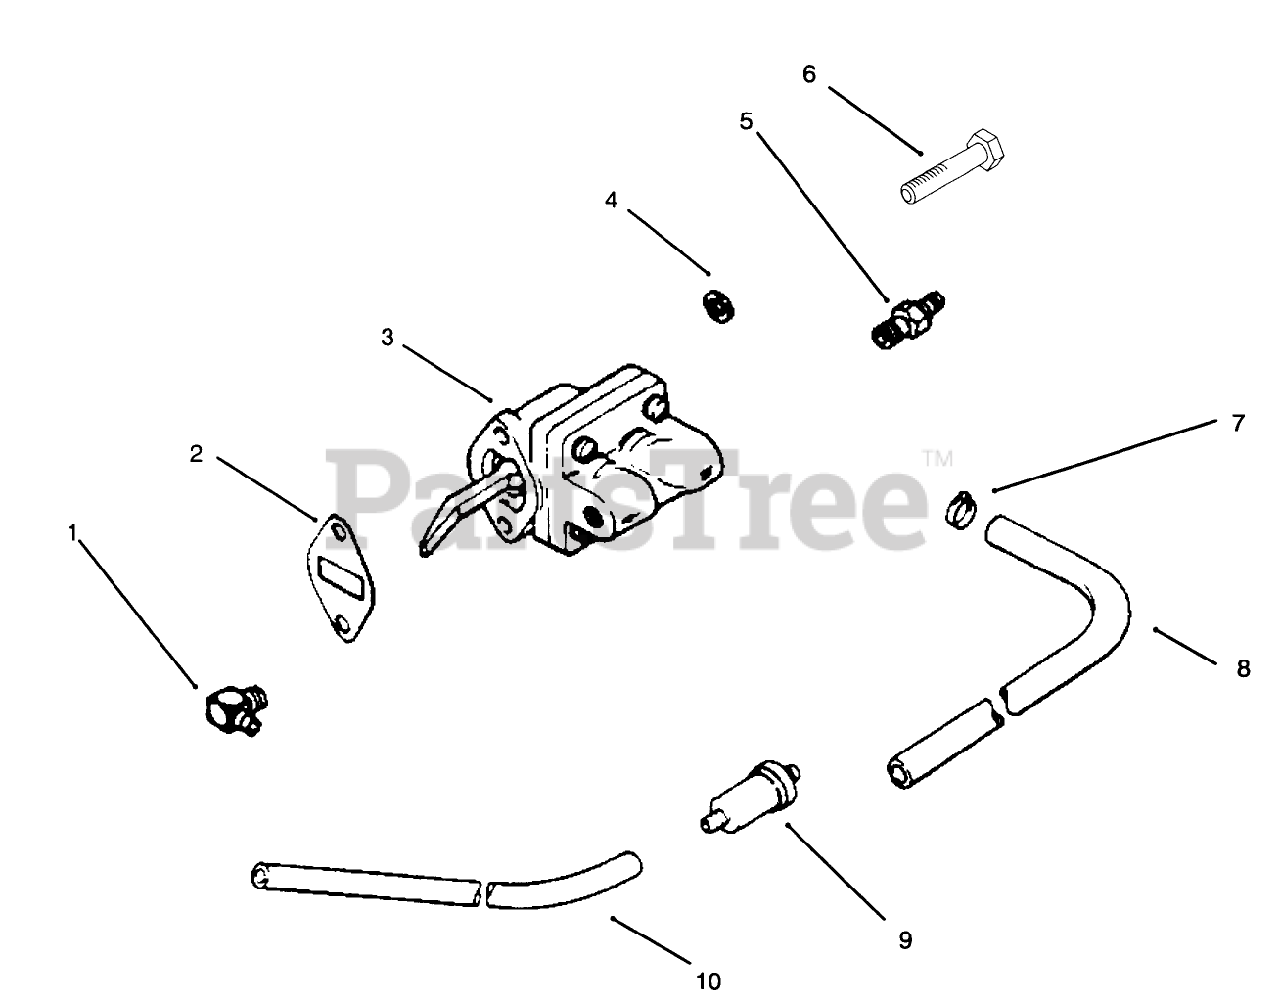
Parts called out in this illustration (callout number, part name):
1	Connector
2	Gasket-Fuel Pump
3	Pump-Fuel (Incl. Ref.#1-5)
4	Washer
5	Connector
6	Screw-Posidriv T.H.
7	Clamp
8	Line-Fuel
9	Filter-Fuel
10	Line-Fuel
